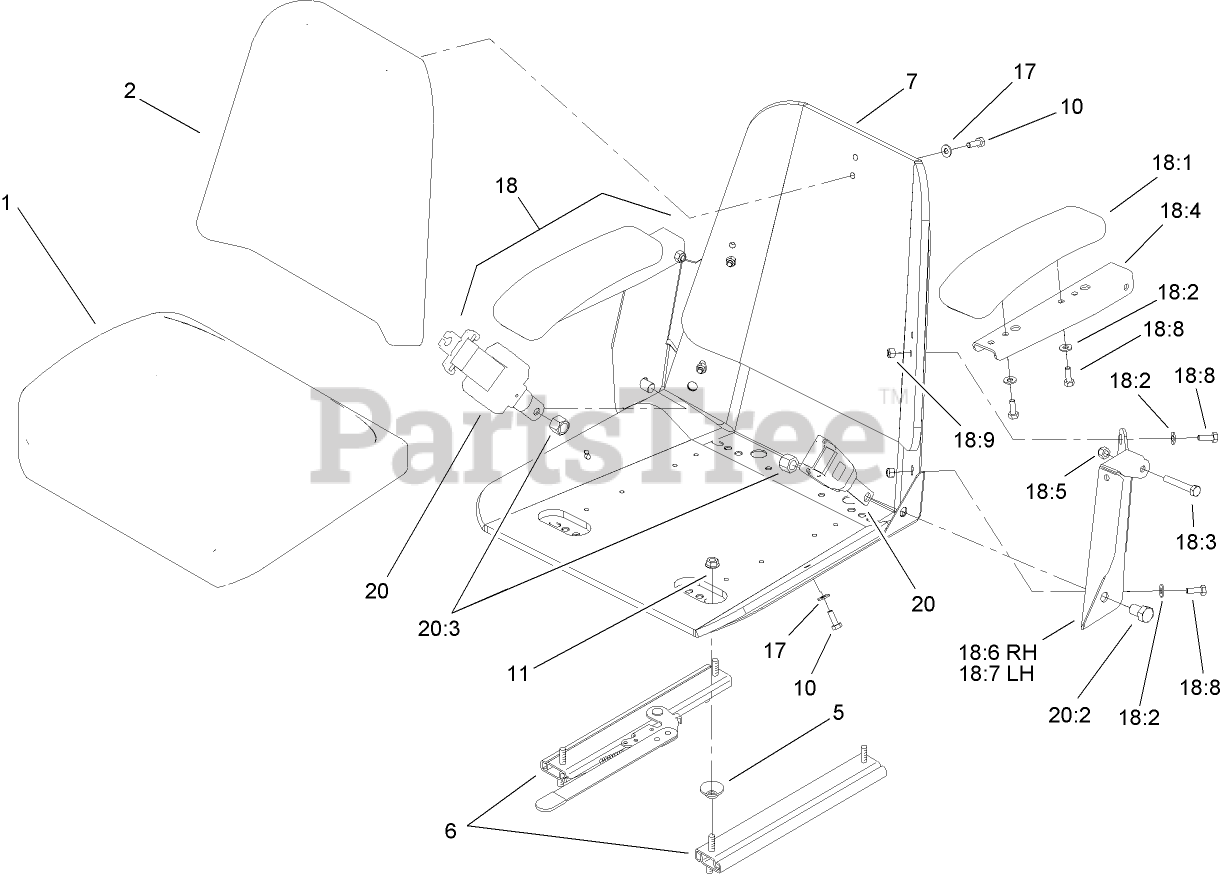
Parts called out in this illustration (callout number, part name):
1	CUSHION-SEAT, BOTTOM
2	CUSHION-SEAT, BACK
5	SPACER-TRACK
6	TRACK-SEAT
7	FRAME-SEAT
10	SCREW-HH
11	NUT-HF
17	WASHER-FLAT
18	ARMREST KIT
18:1	CUSHION-ARMREST
18:2	WASHER-FLAT
18:3	SCREW-HH
18:4	CHANNEL-ARMREST
18:5	NUT-HEX, SIDE DEFORM
18:6	Bracket-Armrest, RH
18:7	Bracket-Armrest, LH
18:8	SCREW-HH
18:9	NUT-LOCK, NI
20	RETRACTABLE SEATBELT KIT
20:2	SCREW-HH
20:3	NUT-LOCK
